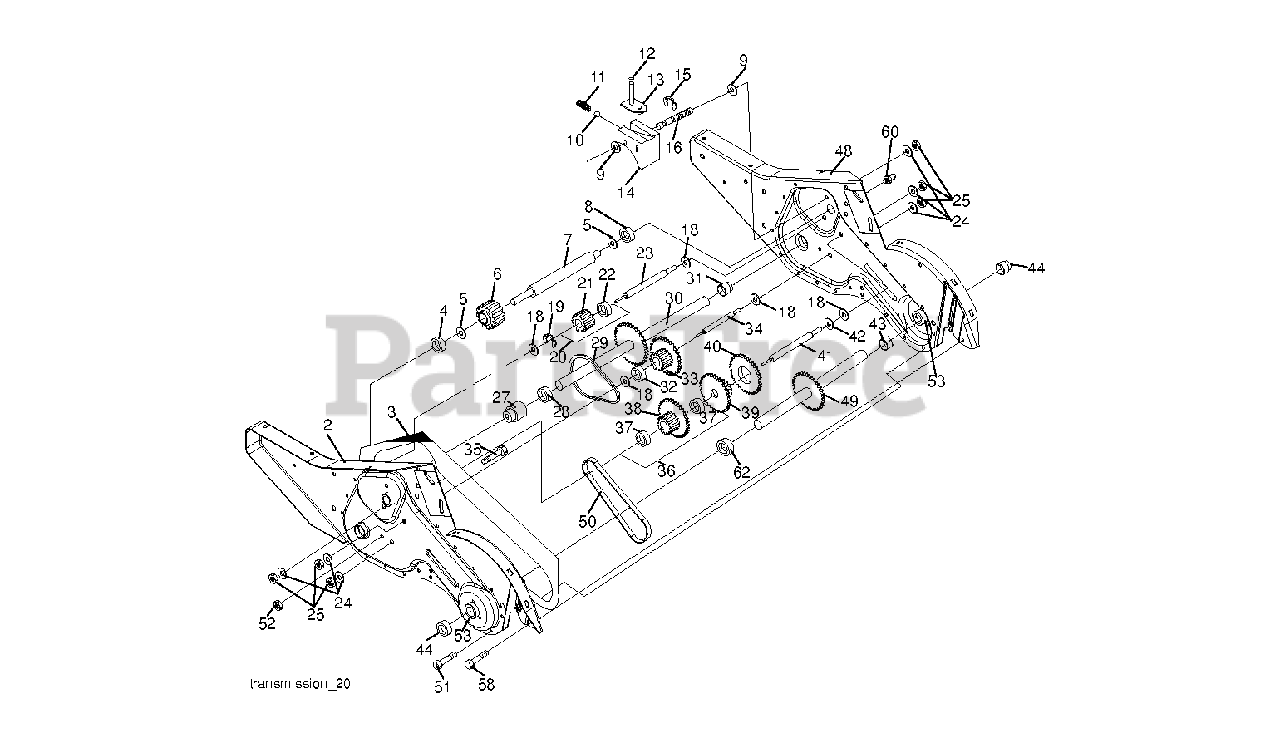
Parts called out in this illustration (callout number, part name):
1	TRANSMISSION ASM.
2	GEARCASE.ASM.CRT.LH.W/BEARING
3	GASKET, GEARCASE
4	NEEDLE BRNG LT
5	THRUST WASHER
6	GEAR.PINION.INPUT
7	SHAFT.INPUT."D".TILLER
8	BEARING TI
9	WASHER, SEAL
10	STEEL BALL KIT
11	SPRING-SHIFT CRT
12	O-RING TI
13	SHIFTING ARM
14	SHIFT FORK TI
15	KLIP RING
16	SHAFT.SHIFTER.TILLER
19	KLIP RING
20	GEAR ASSY CRT
21	GEAR-REV IDLR CRT
22	NEEDLE BEARING TI
23	SHAFT CRT
24	LOCKWASHER
27	BEARING, SHAFT LH CRT
29	CHAIN CRT
30	GROUND SHAFT ASS'Y
31	BEARING, SHAFT RH CRT
32	SPACER TI
33	SPRCKT 8 GEAR CRT
34	SHAFT.SECONDARY.REDUCTION.CRT
35	SCRW WHIZ LOK CRT
36	SPROCKET ASS'Y W/BRG
37	BEARING
38	SPROCKET, TINE
39	GEAR TI
41	SHAFT.REDUCTION.TILLER
42	BRNG RACE T
43	SPACER TI
44	SEAL ASM, OIL
48	GEARCASE.ASM.CRT.RH.W/BEARING
49	SHAFT.ASM.TINE
50	CHAIN.TILLER
51	SCREW
53	BEARING KIT
58	BOLT SHOULDER 1/4-20 UNC X.875
60	FITTING.GREASE.TAPERED
